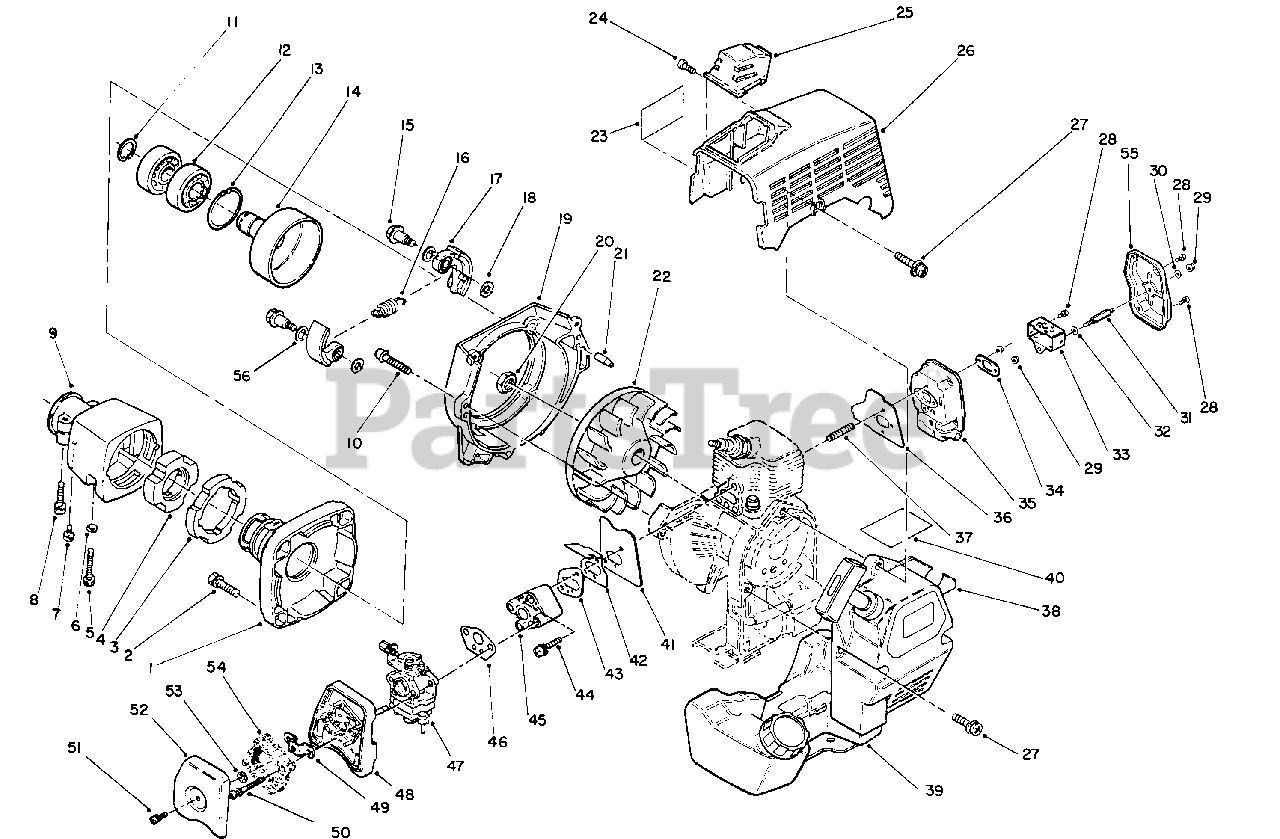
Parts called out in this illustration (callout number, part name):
1	Case-Clutch
2	Bolt/Washer
5	Screw/Washer
6	Washer-Lock
7	Screw/Washer
8	Bolt/Washer
10	Screw/Washer
11	Ring-Retaining
12	Bearing-Ball
13	Ring-Retaining
14	Drum-Clutch
15	Bolt-Clutch
17	Shoe-Clutch
19	Case-Fan
20	Nut-Conical
21	Pin-Dowel
23	Decal-Hot
24	Screw/Washer
25	Guard-Spark Plug
26	Cover-Engine
28	Screw/Washer
29	Nut-Flange Lock
31	Spacer-Threaded
34	Plate
36	Gasket-Muffler
38	Recoil Assembly
39	Tank Assembly-Fuel
40	Decal-Fuel Mix
41	Gasket-Insulator
43	Gasket-Insulator
44	Screw/Washer
45	Insulator
46	Gasket-Carburetor
47	Carburetor Assembly
48	Case-Air Cleaner
50	Screw/Washer
51	Screw/Washer
52	Cover-Air Cleaner
53	Nut-Push
54	Element-Air Cleaner
55	Cover-Muffler
56	Washer-Wave
